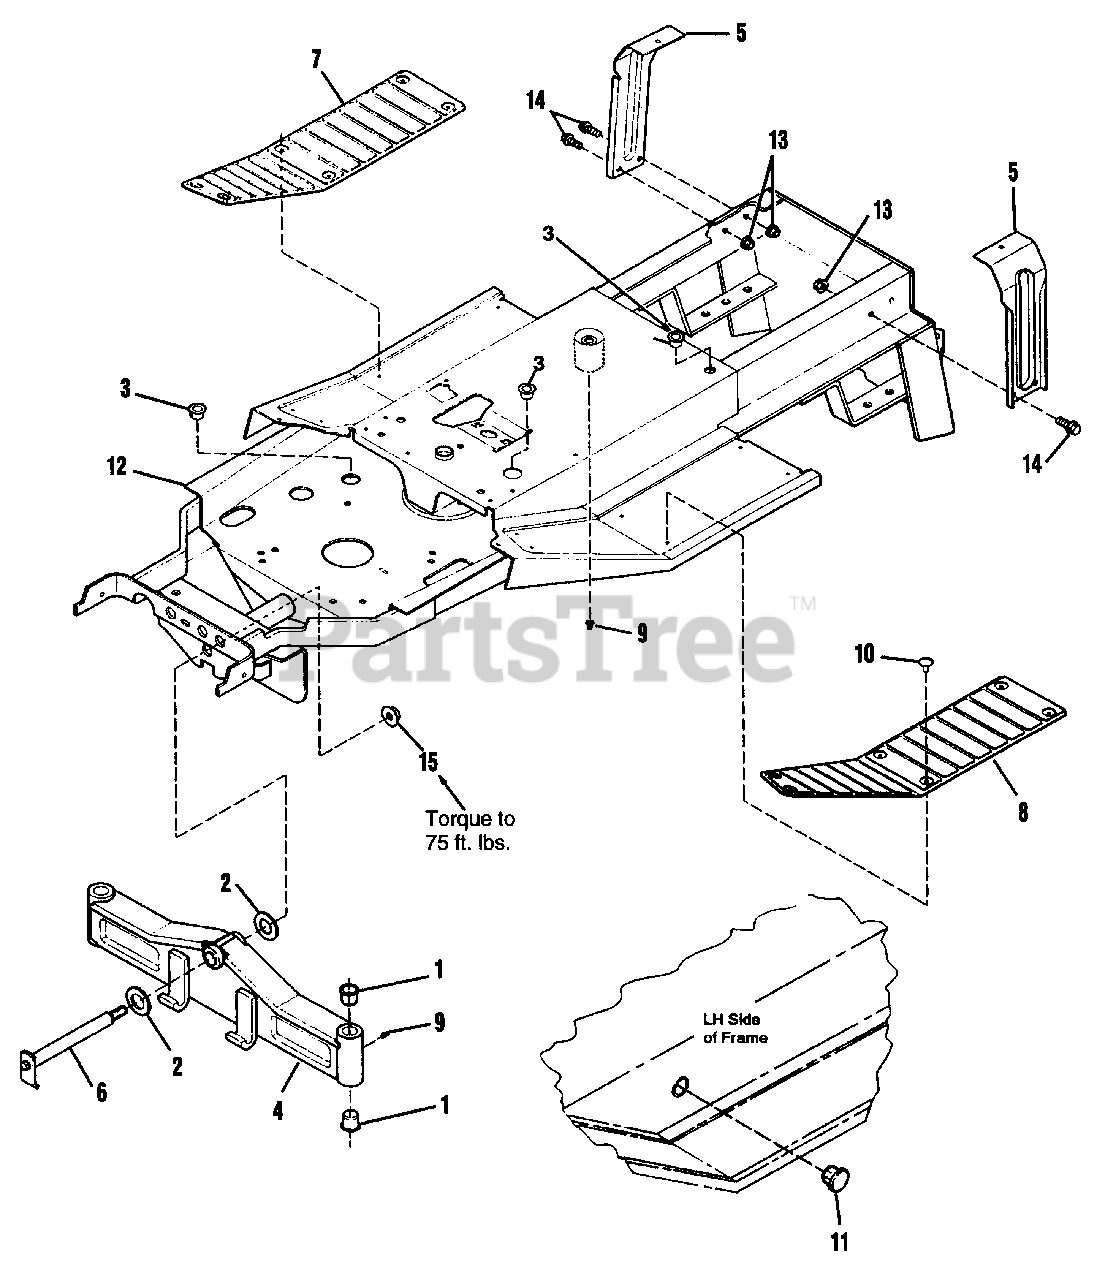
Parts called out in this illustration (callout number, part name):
2	WASHER, Special
3	BUSHING, Snap
4	AXLE ASSY., Front
5	SUPPORT, Seat
6	AXLE PIVOT ASSY.
7	PAD, Footrest, RH
8	PAD, Footrest, LH
9	GREASE, Fitting
10	FASTENER, Panel
11	PLUG, Button
12	FRAME ASSY.
13	NUT, Hex, Esna Lock, 3/8-16
14	CAPSCREW, Hex Whizlock, 3/8-16 x 1
15	NUT, Hex, Full Lock, 3/4-16
